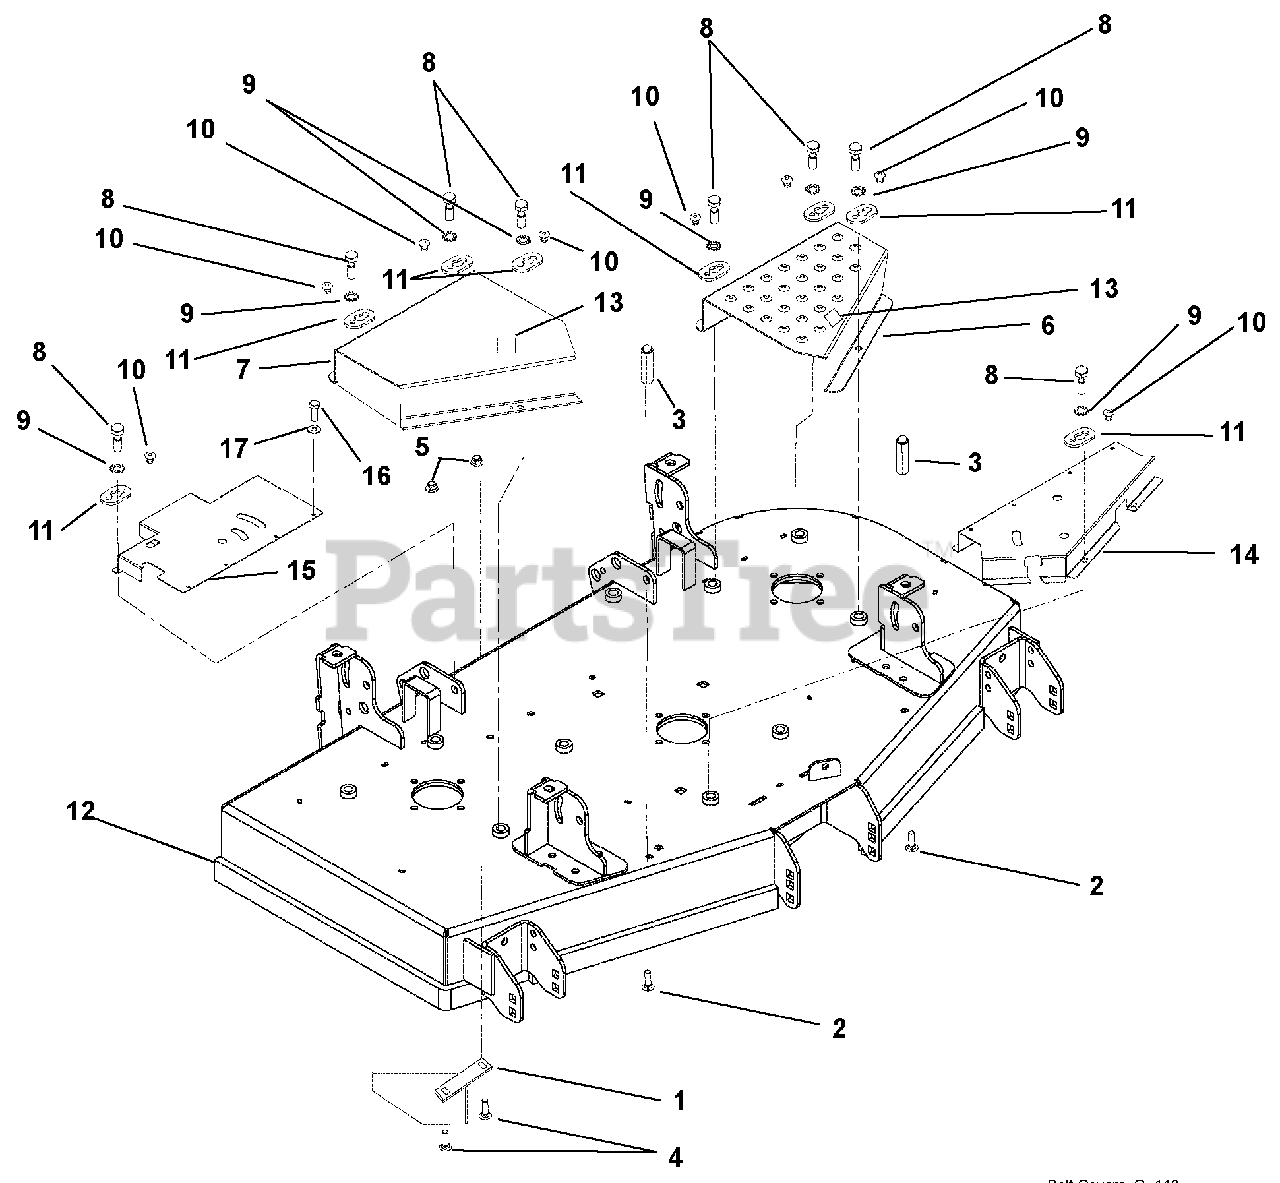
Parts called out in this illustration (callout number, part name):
1	Rear Discharge Deflect Baffle Weldment
2	Bolt, Round Head Square Neck .31-18 x .75
3	Nut, Coupling .31-18 x 3.00
4	Bolt, Round Head Square Neck .38-16 x 1.00
5	Nut, Locking-Nylon-Flange .38-16
6	Cover, Belt, CE Left Hand
7	Cover, CE Belt Right Hand
8	Bolt, Hex .38-16 x 1.25
9	Washer, Locking, EXT .391 x .682 x .036
10	Rivet, Pop .187
11	Keeper, Bolt
12	Weldment, 48" PT100 RR DISCH Deck
13	Decal, Pinch Point
14	Weldment, Front Belt Shield
15	Shield, Belt Rear
16	Bolt, Hex .25-20 x .75 Grade 5 YZ
17	Washer, Flat Steel .281 x .62 x .065 YZ
